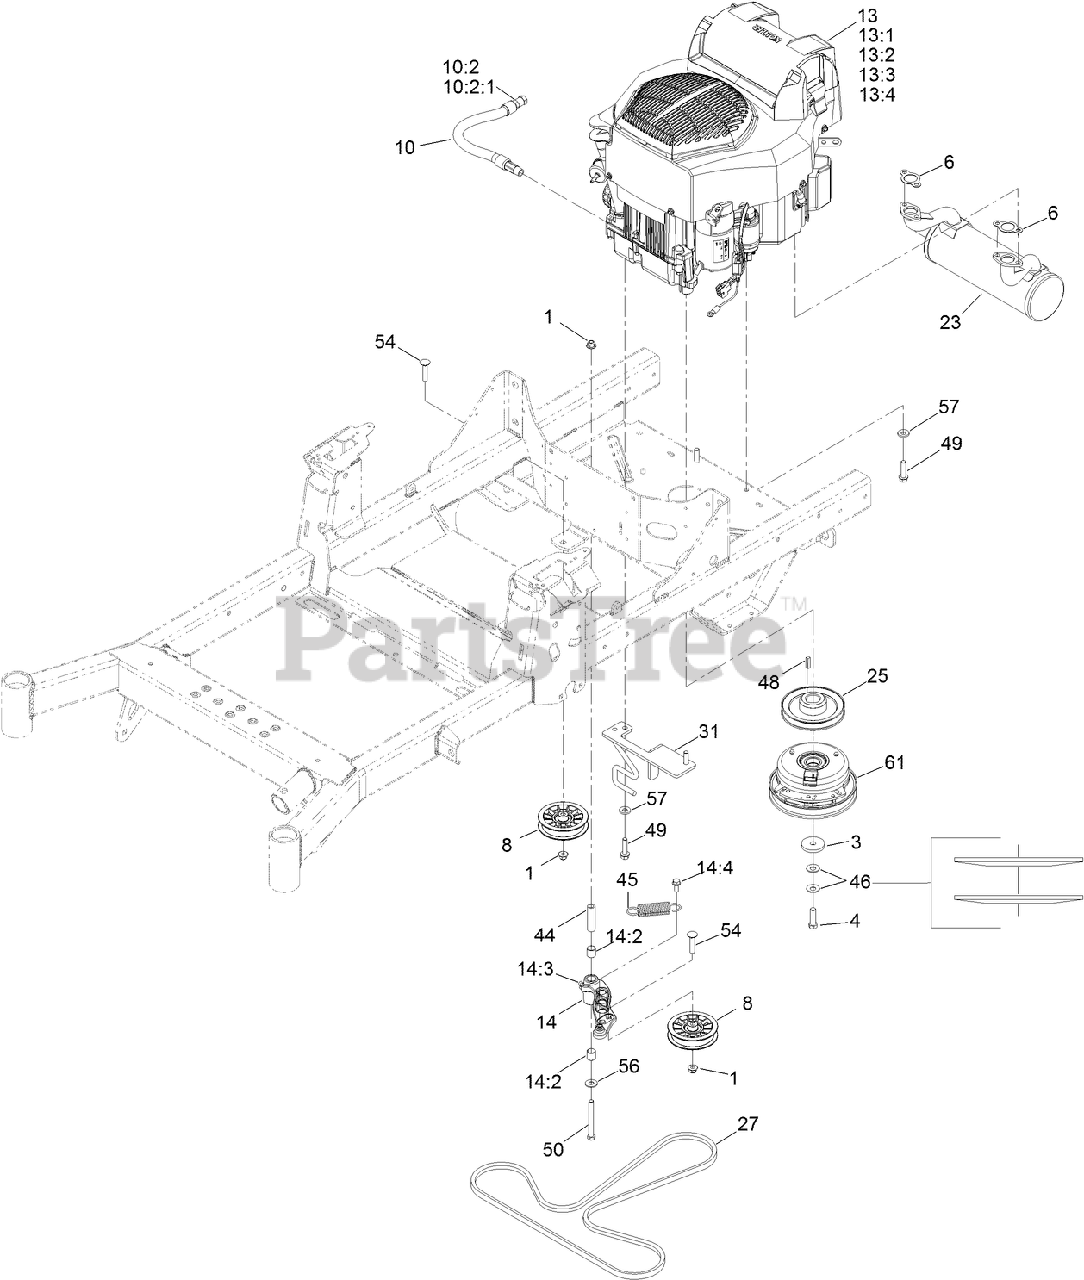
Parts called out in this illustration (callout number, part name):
1	NUT-HF, NI
3	WASHER-CLUTCH
4	SCREW-HH, W/LOCTITE
8	PULLEY-FLAT IDLER
10	OIL DRAIN HOSE ASM
10:2	PLUG-HH
10:2:1	O-RING
13:1	KOHLER 16 083 01-S ENGINE AIR FILTER
13:2	KOHLER 52 050 02-S ENGINE OIL FILTER
13:3	KOHLER 24 050 13-S FUEL FILTER
13:4	KOHLER 25 083 04-S SAFETY FILTER
14	IDLER ARM ASM
14:2	SLEEVE-BEARING
14:3	FITTING-GREASE, 90 DEG
14:4	SCREW-THD ROLL, HWH
23	MUFFLER-KOHLER AES
25	SHEAVE (W/HUB)
27	BELT-V
31	ANCHOR-CLUTCH
44	BUSHING-PIVOT, IDLER
45	SPRING-EXTENSION
46	WASHER-SPRING
49	SCREW-HWH
50	SCREW-HH
54	SCREW-CARR
56	WASHER-FLAT
57	WASHER-BELLEVILLE
61	CLUTCH
